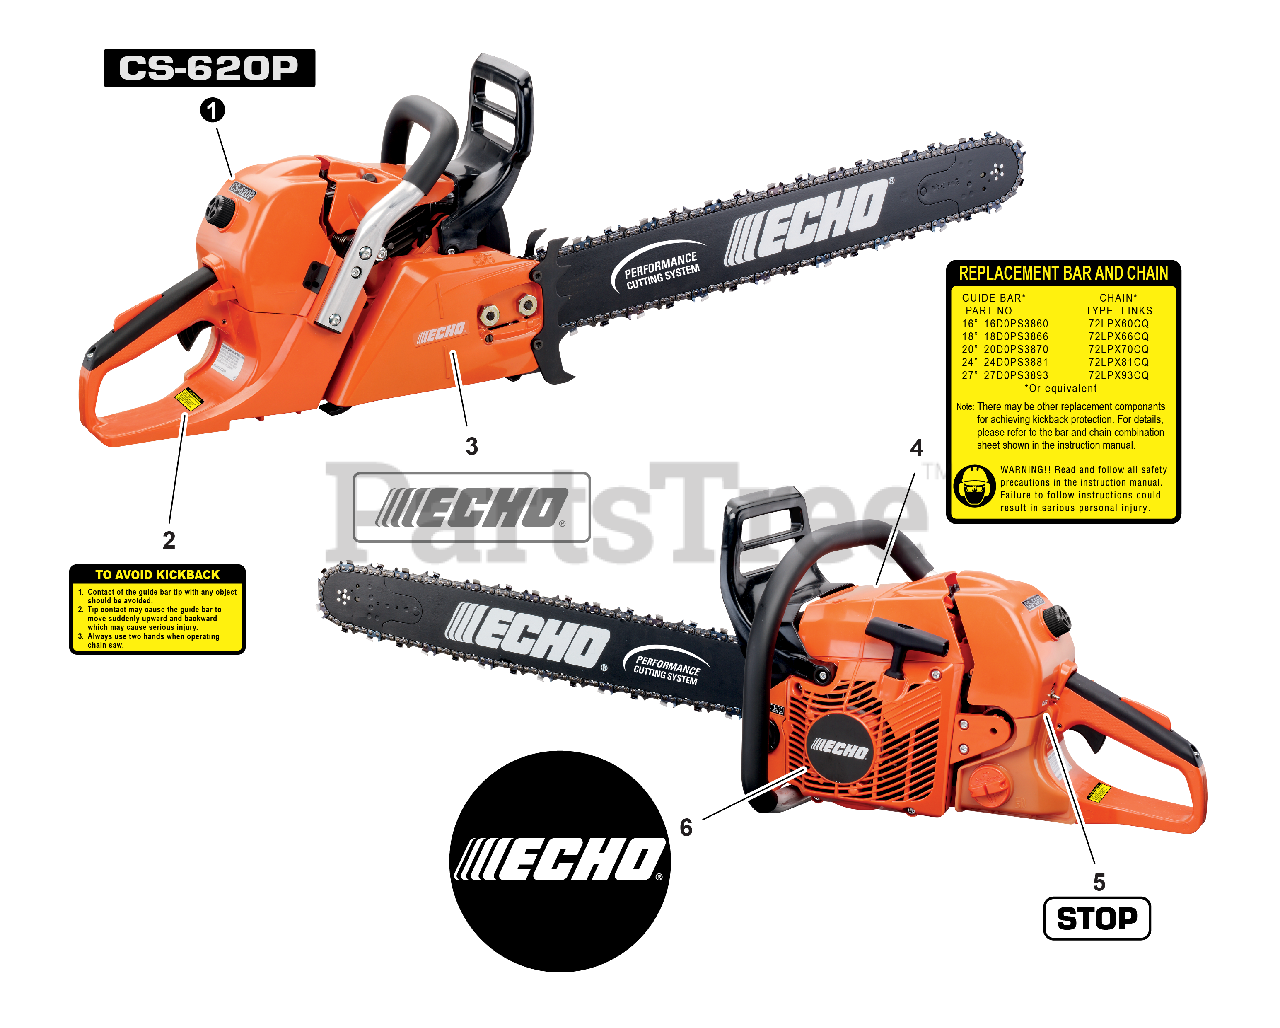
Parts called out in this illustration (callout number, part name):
1	LABEL - MODEL -- CS-620P
2	LABEL - KICKBACK
3	LABEL - ECHO
4	LABEL - BAR & CHAIN
5	LABEL - STOP
6	LABEL - ECHO
